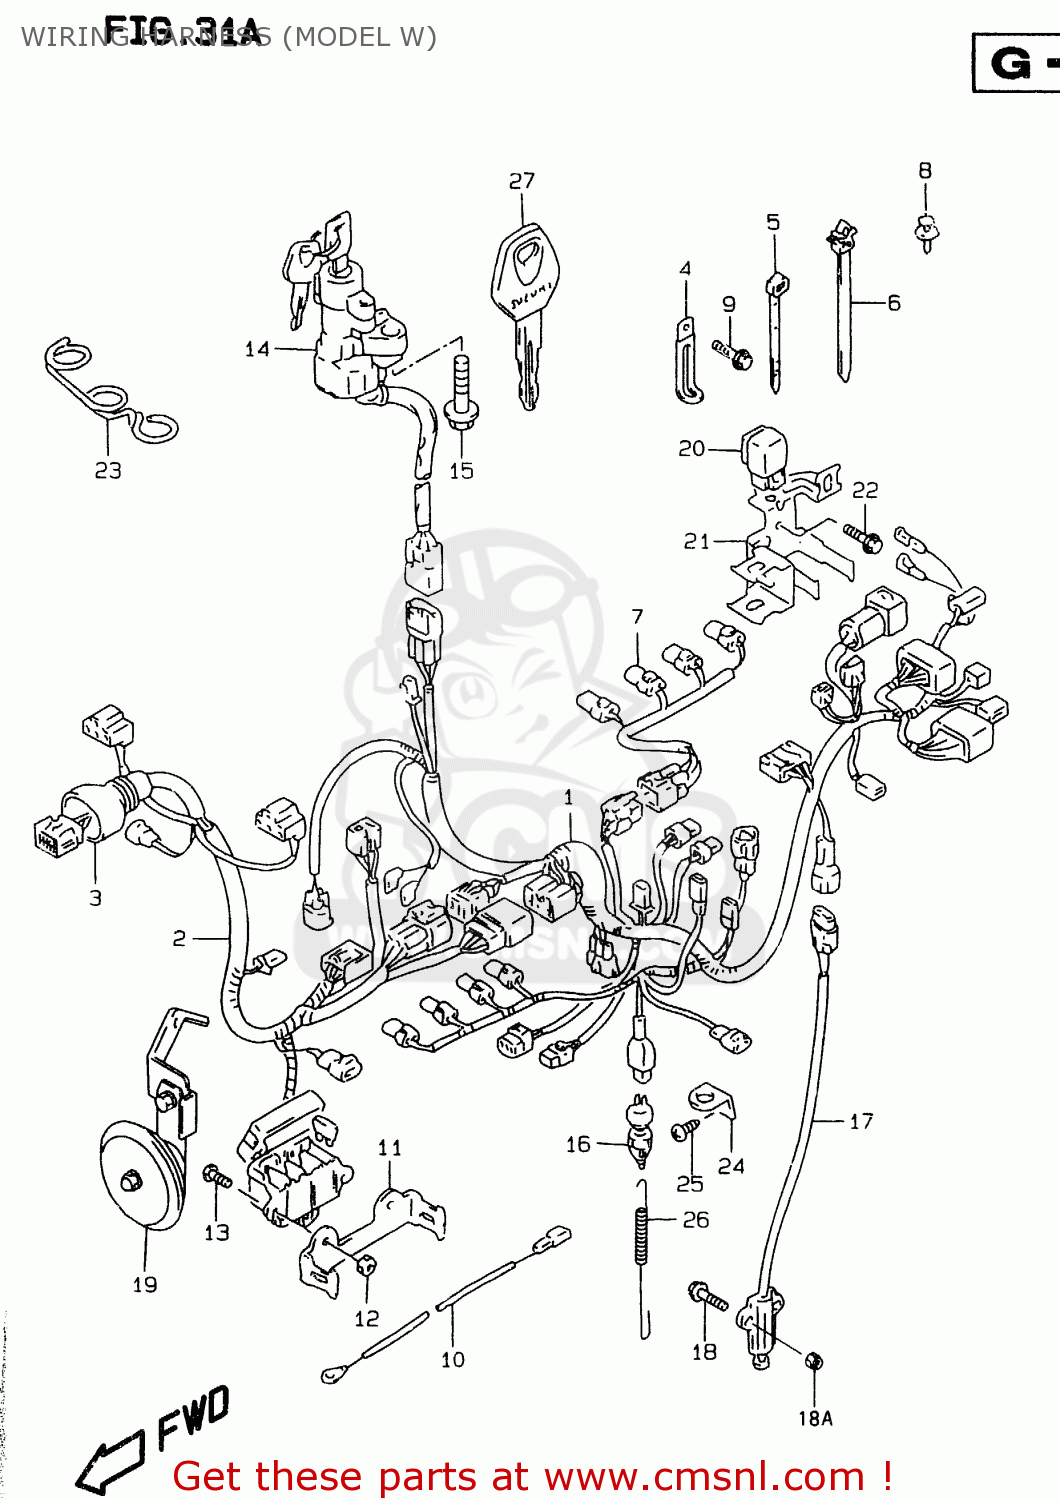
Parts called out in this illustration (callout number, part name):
1	HARNESS,WIRING NO.1
2	HARNESS,WIRING NO.2
3	COVER,SPEEDOMETER COUPLER
4	CLAMP(L:45)
5	CLAMP(L:125)
6	CLAMP
6A	SCREW 6X12
7	WIRE,INJECTOR LEAD
8	CLIP(BLACK)
9	BOLT
10	WIRE,OIL PRESSURE SWITCH LEAD
11	BRACKET,FUSE BOX
12	NUT,COWLING SCREEN
13	SCREW 5X12
14	LOCK ASSY,STEERING
15	BOLT(8X20)
16	SWITCH ASSY,STOP LAMP
17	SWITCH ASSY,SIDE STAND WARNING
18	BOLT
18A	NUT
19	HORN ASSY
20	RELAY ASSY
21	BRACKET COMP,FUEL PUMP RLY
22	BOLT
23	GUIDE,WIRING HARNESS
24	BRACKET,STOP LAMP SWITCH
25	SCREW
26	SPRING
27	KEY,BLANK
